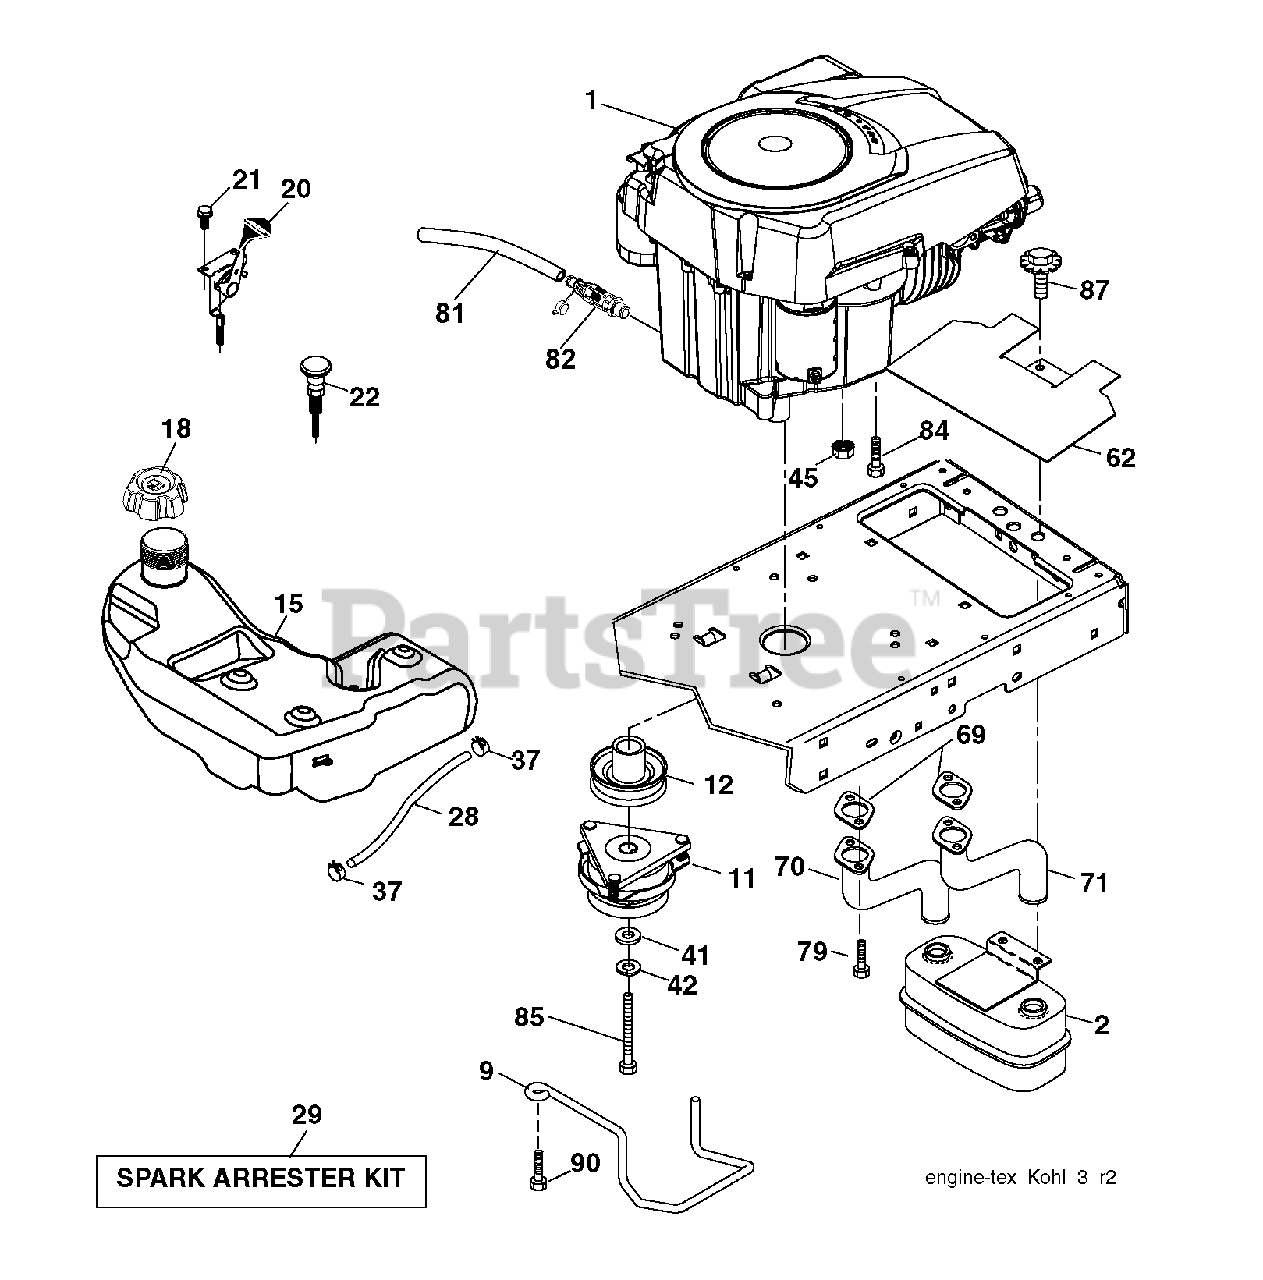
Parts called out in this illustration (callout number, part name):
2	MUFFLER.TWIN.CYL.LOW.TONE
9	KEEPER.BELT.ENGINE.4.2
11	RB.CLUTCH.OGURA.4.4.PD
12	PULLEY.ENGINE.TUFFTORQ
15	TANK.FUEL.4GAL
18	CAP.FL.R.3'N/CARB.H.CROWN.498
20	THROTTLE CONTROL
21	SCREW.#10 X 0.750.BOS
22	CONTROL.CHOKE.ERGO.PUSH-IN.BLA
28	REPL BY 532 00 85-43
29	KIT.SPARK ARRESTOR 794945 B&S
37	HOSE CLAMP
42	LOCKWASHER
45	NUT
62	SHIELD.HEAT.MUFFLER
69	GASKET.EXHAUST.KOHL.CV18-CV26
70	RP.PIPE-EXHAUST LH
71	RP.PIPE-EXHAUST RH
79	SCREW.SOCKET HD.5/16-1
81	TUBE, DRAIN OIL ASM.
82	VALUE.OIL.DRAIN
84	SCREW 3/8-16X1
85	BOLT HEX 7/16-20X4-1/4"
87	BOLT, 5/16-18 X 1 3/4
90	SCREW 3/8-16X1
